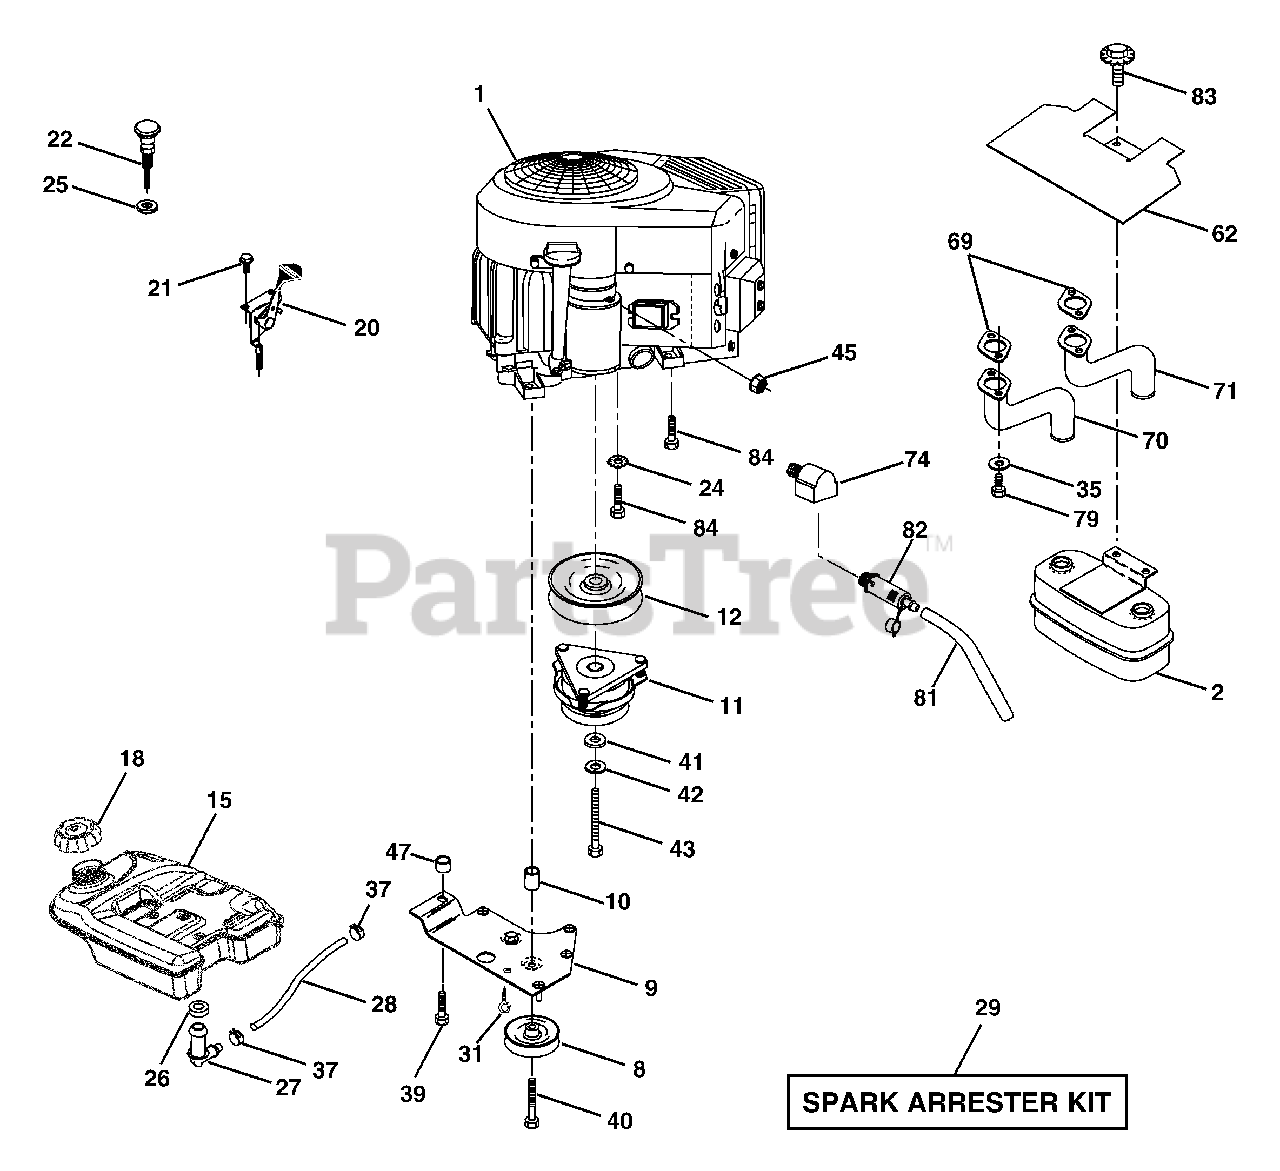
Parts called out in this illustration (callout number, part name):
2	Muffler Side
8	Pulley V-Idler
9	Keeper Asm. Belt Engine VGT
10	Bushing
11	Clutch Electric
12	Pulley Engine VGT Elect Clutch
15	Tank Fuel Rear 5.0
18	Cap Asm. Fuel
20	Control Throttle
21	Screw Hw Hd Hi-Lo #13-16 x 3/4
22	Control Choke
24	Washer Ext Tooth 3/8
25	Nut Keps 3/8-24 Unf
26	Bushing
27	Stem Tank Fuel
29	Spark Arrester Kit
31	Clip
35	Washer
37	Clamp Hose
39	Screw TT 3/8-16 x 2-1/4 UNC
40	Screw TT 3/8-16 x 4 UNC
41	Washer 1-1/2 OD X 15/32 ID X .250
42	Washer Lock 7/16
43	Bolt Hex 7/16-20 x 3.75 Gr. 5
45	Nut Keps Hex 1/4-20
47	Spacer
62	Shield Heat Muffler CV-Intek
69	Gasket
70	Tube Exhaust LH
71	Tube Exhaust RH
74	Elbow Street Brass
79	Screw Hex Hd Cap 5/16-18 x 3/4
81	Tube Drain Oil Easy
82	Plug Oil Drain Easy
83	Bolt 5/16-18unc X 1-3/4 W/Sems
84	Screw Thdrol 3/8-16 x 1-1/2
